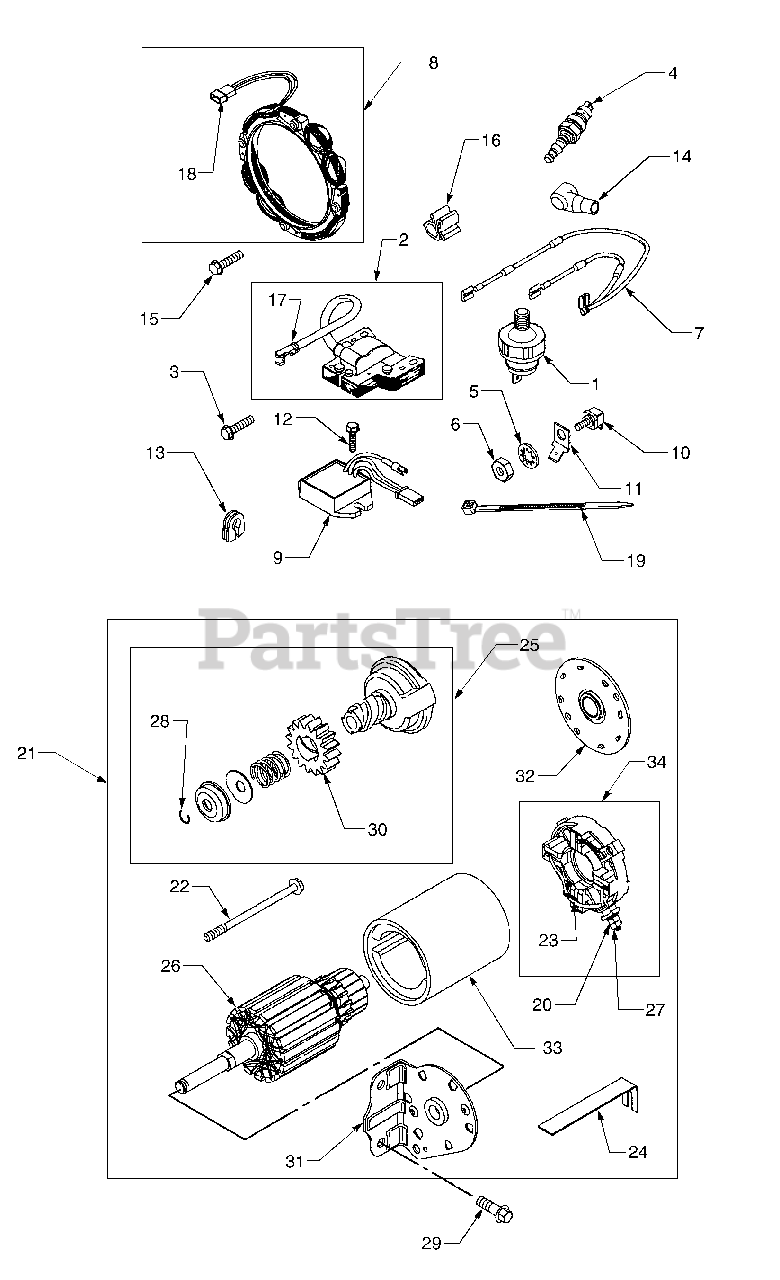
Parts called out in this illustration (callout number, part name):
1	Switch, Oil Pressure
2	Armature, Magneto
3	Screw, Hex
4	Spark Plug
5	Washer, Lock
6	Nut, Hex
7	Wire, Ground
8	Stator, Alternator
9	Regulator, Alternator
10	Insulator
11	Terminal
12	Screw, Hex
13	Grommet
14	Boot, Spark Plug
15	Screw, Hex
16	Clip, Wire
17	Terminal, Ignition Cable
18	Diode and Connector Assembly
19	Tie, Cable
20	Washer, Flat
21	Motor, Starter
22	Screw, Hex
24	Strap, Starter
25	Starter Drive Group
26	Armature Assembly
27	Nut, Hex
28	Ring, Retaining
29	Screw, Hex
30	Gear, Starter
31	Drive End Cap Assembly
32	End Cap Assembly - Commutator 1
33	Housing Assembly
34	Retainer, Brush
